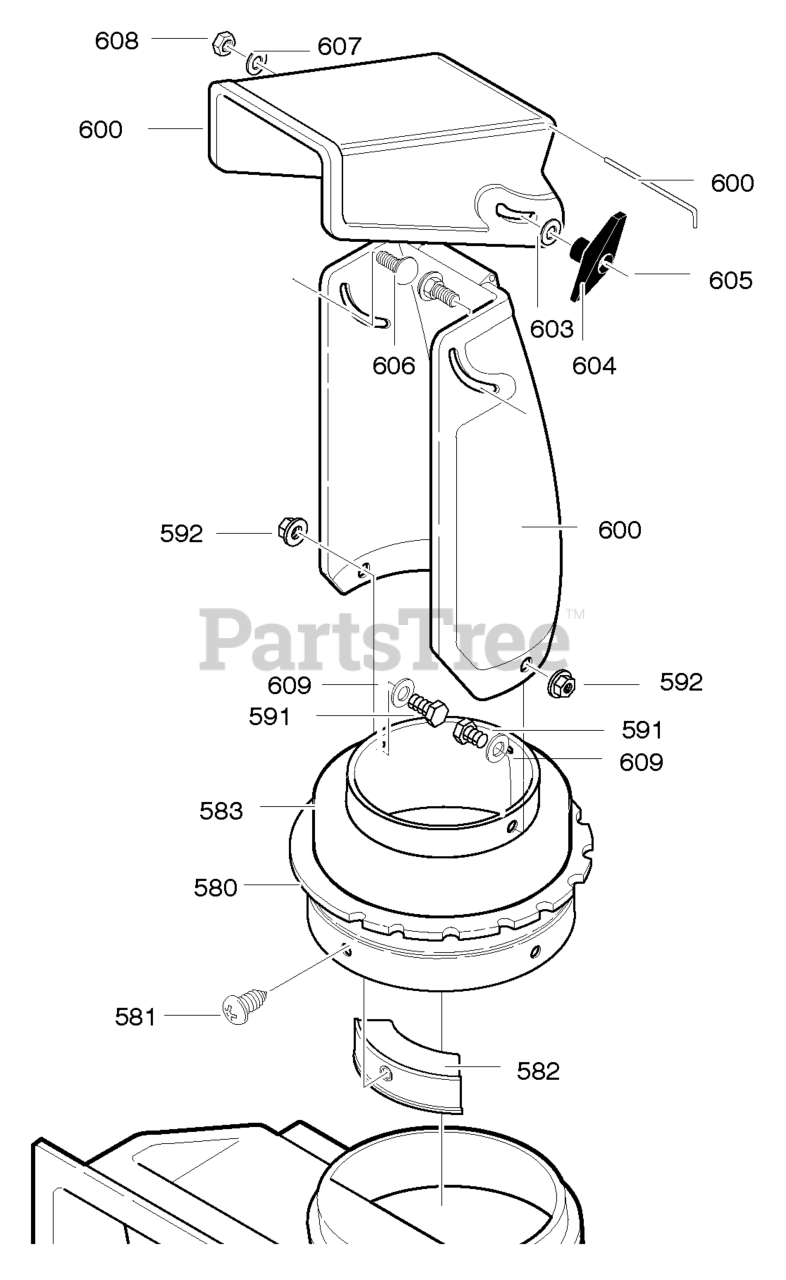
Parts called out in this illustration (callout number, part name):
580	RING, CHUTE
581	SCREW, #10X.50
582	GUIDE, CHUTE
583	DONUT FOAM
591	SCREW 1/4-20X.50
592	NUT, 1/4-20
600	CHUTE ASSY
602	BOLT, 5/16-18X1.25 CARR.
603	WASHER, FLAT
604	KNOB, T
605	NUT, 5/16-18
606	SCREW, 5/16-18 x 0.75
607	WASHER, FLAT .349X.69X.066
608	NUT, 5/16-18
609	WASHER, FLAT
